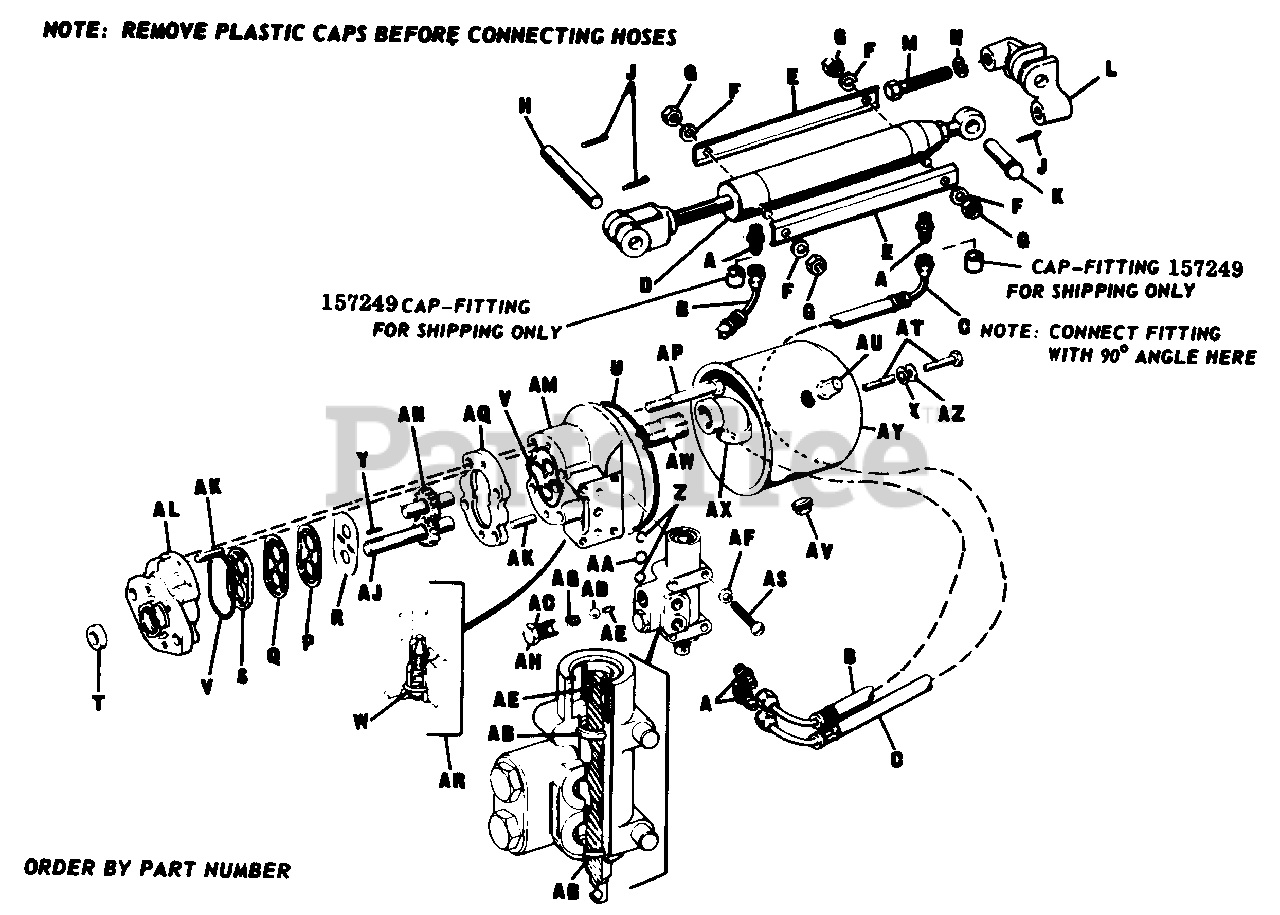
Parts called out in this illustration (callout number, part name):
B	Hose Assembly
C	Hose Assembly
D	Cylinder Assembly
F	Lock Washer, 5/16"
G	Full Hex. Nut, 5/16"-18
J	Cotter Pin, 1/8" x 3/4"
K	Ram Bracket Pin
L	Ram Bracket
M	Hex. Cap Screw 7/16"-14 x 2-1/4"
N	Lock Washer, 7/16"
P	Heat Shield (for Service only)
R	Wear Plate
T	Rotary Seal
X	Stat-O-Seal
Y	Shaft Drive Key
AF	Lock Washer 1/4"
AJ	Drive Gear Assembly
AK	Dowel Pin
AL	Front Cover Assembly
AM	Back Cover Assembly
AN	Driven Gear Assembly
AQ	Center, Section Machined
AR	Relief Valve Assembly
AU	Filler Cap Plug
AV	Drain Plug
AW	Inlet Nipple
AX	Inlet Elbow
AY	Tank Assembly
AZ	Flat Washer, 1/4"
